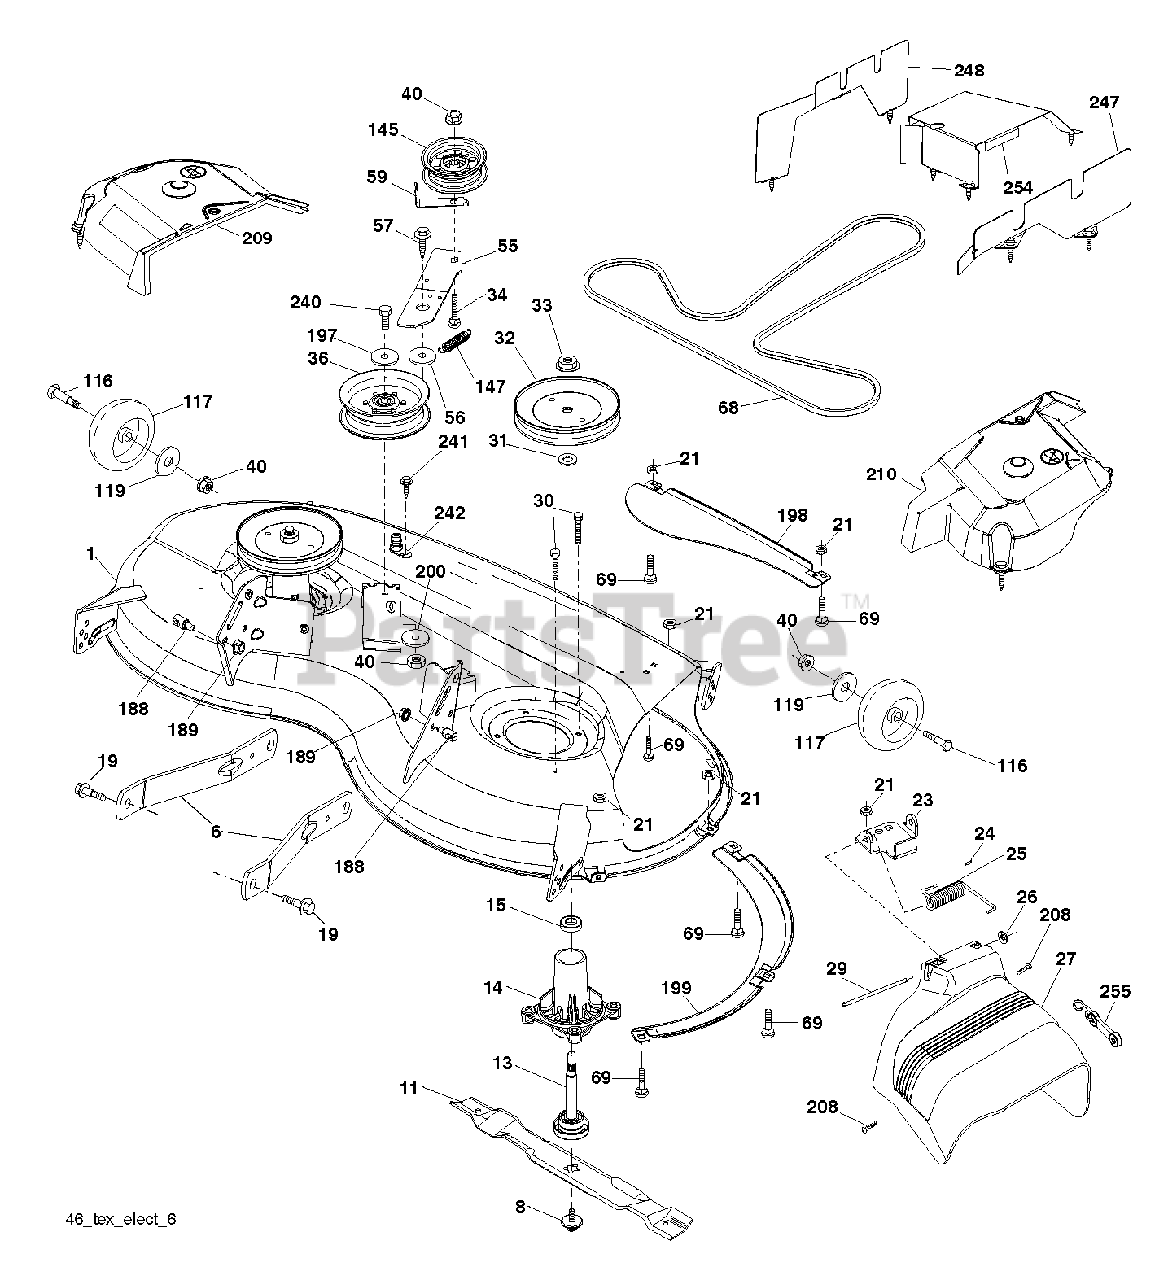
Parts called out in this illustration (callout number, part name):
1	DECK.WLDMT.W/TB.46.4GA.TTR
6	ARM.SUSPENSION.MOWER.R
8	BOLT.WASHER.ASM.7/16-2
11	BLADE.MOWER.46".HI.LIFT
13	SHAFT.ASM.MDRL.N/GREASE.38
14	HOUSING.MANDREL.4PT.
19	BOLT.SHOULDER
21	LOCKNUT
23	BRKT.DEFLECTOR.38"2005+
24	CAP-SLEEVE LT
25	SPRING.TORSION.DEFLECT
26	NUT PUSH M
27	SHIELD SUBASM DEFLECTOR 46 FRE
29	ROD.HINGE
30	SCREW, WASHER HEAD
31	WASHER.SPACER.MANDREL
32	PULLEY.MANDREL.5.438.PD
33	NUT.FLANGE.LOCK.TOP
34	BOLT.3/8-16X1.50
36	PULLEY.IDLER.2006
40	NUT LOCK FLG 3/8-16 UNC
56	SPACER.RETAINER
57	SCREW 3/8-16X1
59	GUARD, BELT
68	V-BELT
69	BOLT
116	BOLT.SHOULDER.3/8-16X3-5/8.
117	WHEEL. GUAGE RALLY
119	WASHER
145	PULLEY.IDLER.48"PRIMARY
147	SPRING.MOWER.DRIVE.ELECTRIC
188	STUD.FASTNER.W/ANTI-ROTATE
189	NUT LOCK HEX FLANGE 5/16-18
197	WASHER
198	BAFFLE CENTER FRONT
199	BAFFLE FRONT RH
200	WASHER.13/32 X 1 X 1/2.11GUARD
208	SCREW 3/8-16X1/2
209	COVER MANDREL LEFT
210	COVER MANDREL RIGHT
240	BOLT-HEX EAK
241	SCREW.TT.#10-32X.5.3/8.FLANGE
242	PORT.WASHOUT
247	SHIELD RIGHT
248	SHIELD LEFT
254	SHIELD ASSEMBLY 46 TEX REAR DE
255	ELASTIC STRAP KIT
